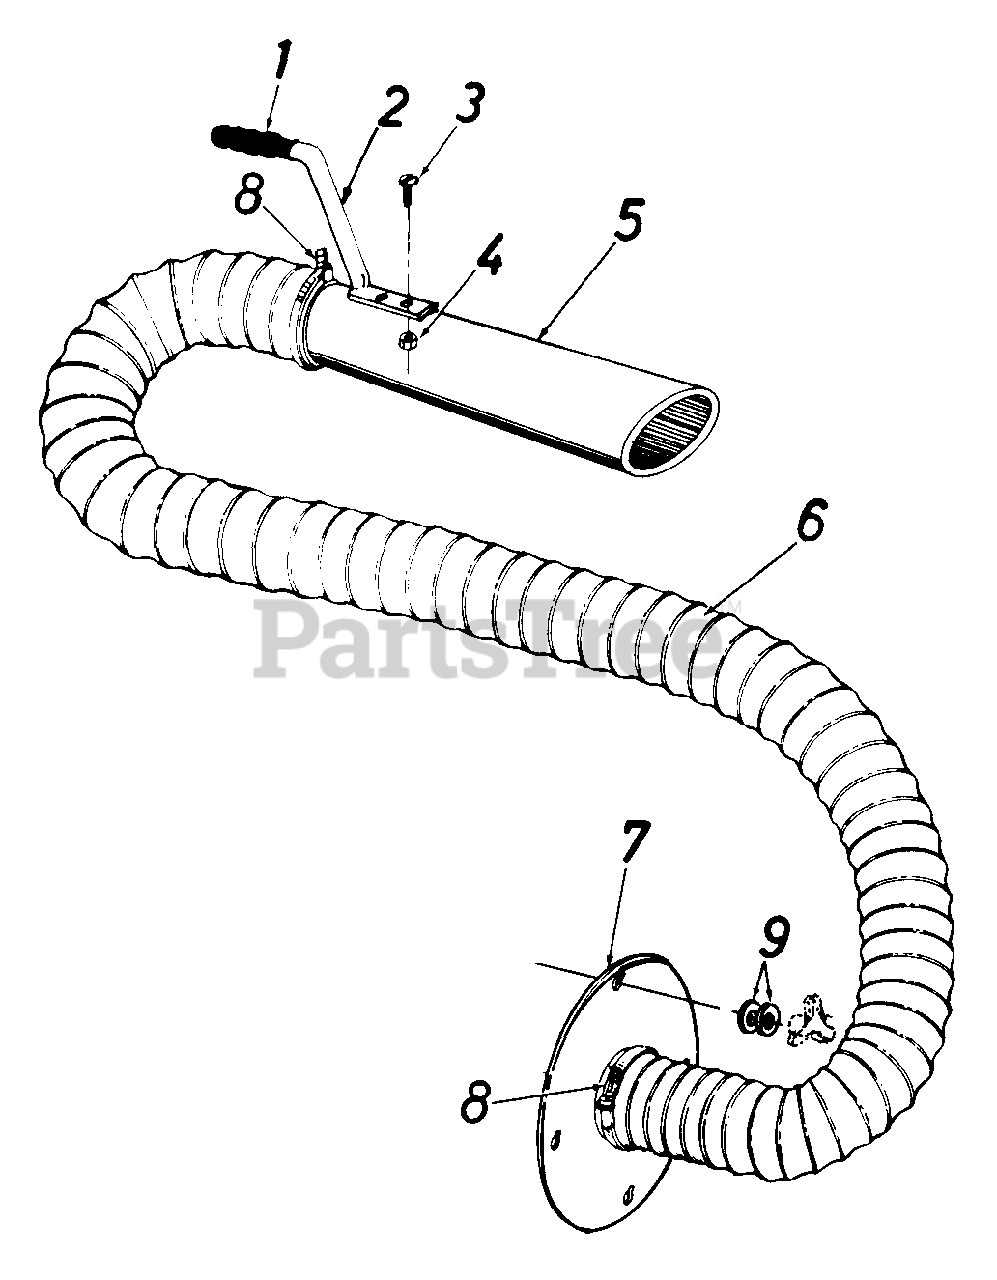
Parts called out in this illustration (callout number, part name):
1	Handle Grip
2	Handle
3	Truss Sems Scr. 10-24 x 1/2" Lg."
4	Hex Nut 10-24 Thd.
5	Hose Nozzle
6	Flexible Hose 4" Dia. x 10' Lg.
9	Flat Washer .34 I.D. x 1.12 O.D.
